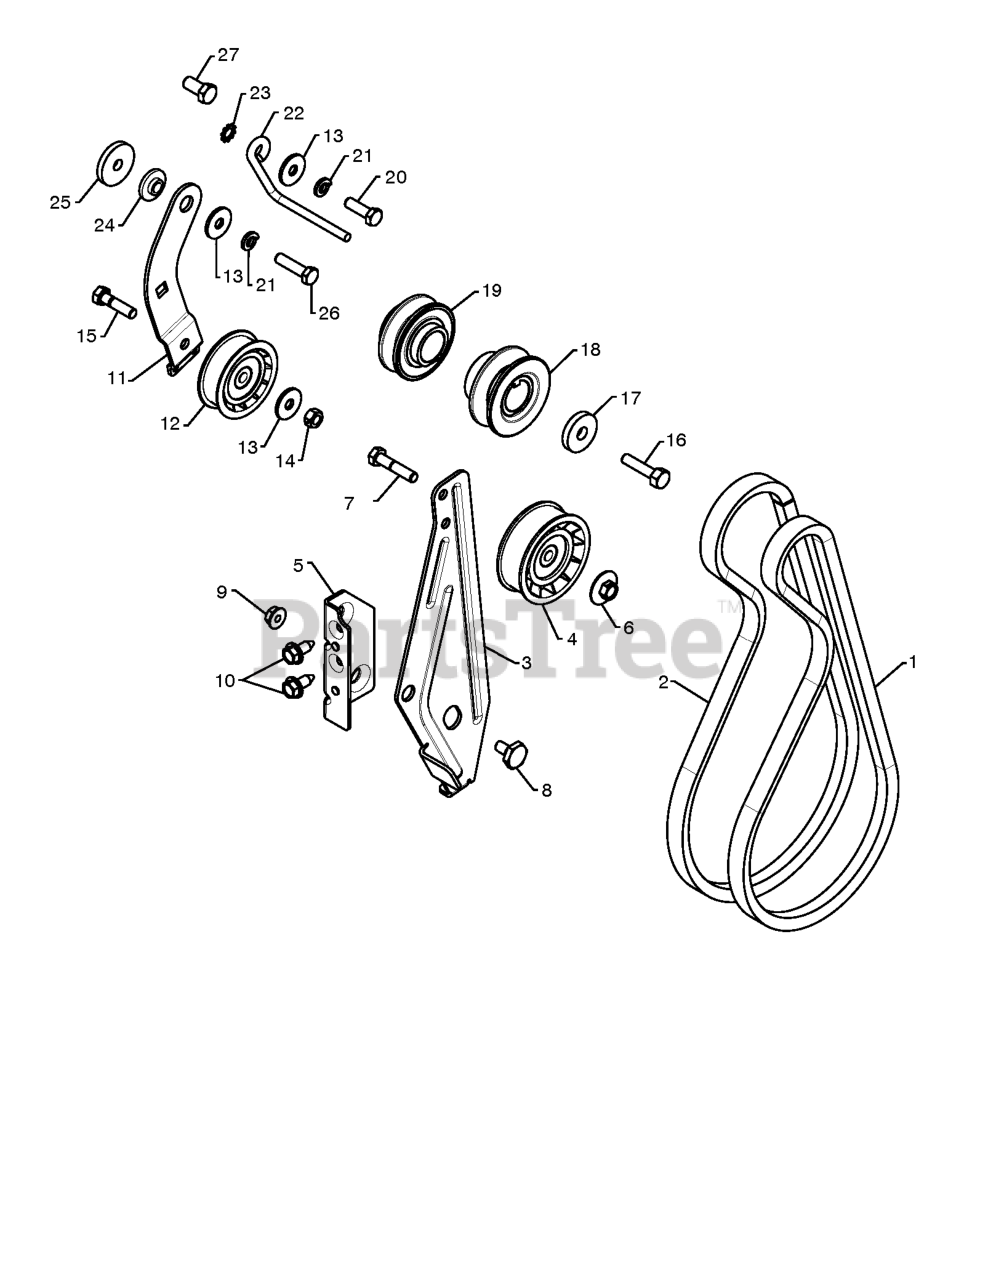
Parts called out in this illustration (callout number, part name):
1	V-BELT.IMPELLER
2	TRACTION BELT
3	ARM.IDLER.BRAKE.PNT.BLACK
4	PULLEY.W/SPACER.2.75
5	RP.BRACKET.IDLER.PIVOT.BLACK
6	NUT.FLANGE.HEX.5/16X18.BLACK
7	HEX BOLT
8	BOLT.SHOULDER.1/2X12
9	NUT.LOCK.5/16-18
10	BOLT.HEX.HD.WASHER.5/16-18X.75
11	RP ARM.ASM.TRACTION.IDLER
12	PULLEY.W/SPACER.2.25
13	STEEL WASHER
14	NUT.71038.31-18.HEX.NYLOCK
15	BOLT.5/16-18X1-1/4 FULL.THREAD
16	SCREW, HEX HD 3/8-24 X 1-3/8
17	WASHER.400X1.25X5.
18	PULLEY ENG IMPELLER
19	PULLEY.ASM.ENG.TRACTION.1.00
21	WASHER.LOCK.HVY.HLCL.SPR.5/16
22	BELT.GUIDE.RH
23	WASHER EXT TOOTH LOCK 5/16
24	RP BUSHING, IDLER PIVOT
25	WASHER.FLAT.34X1.38X22
26	CAPSCREW.HEXHD.5/16X1.25.
27	SCREW.3/8-16 X .750 (2 2)
